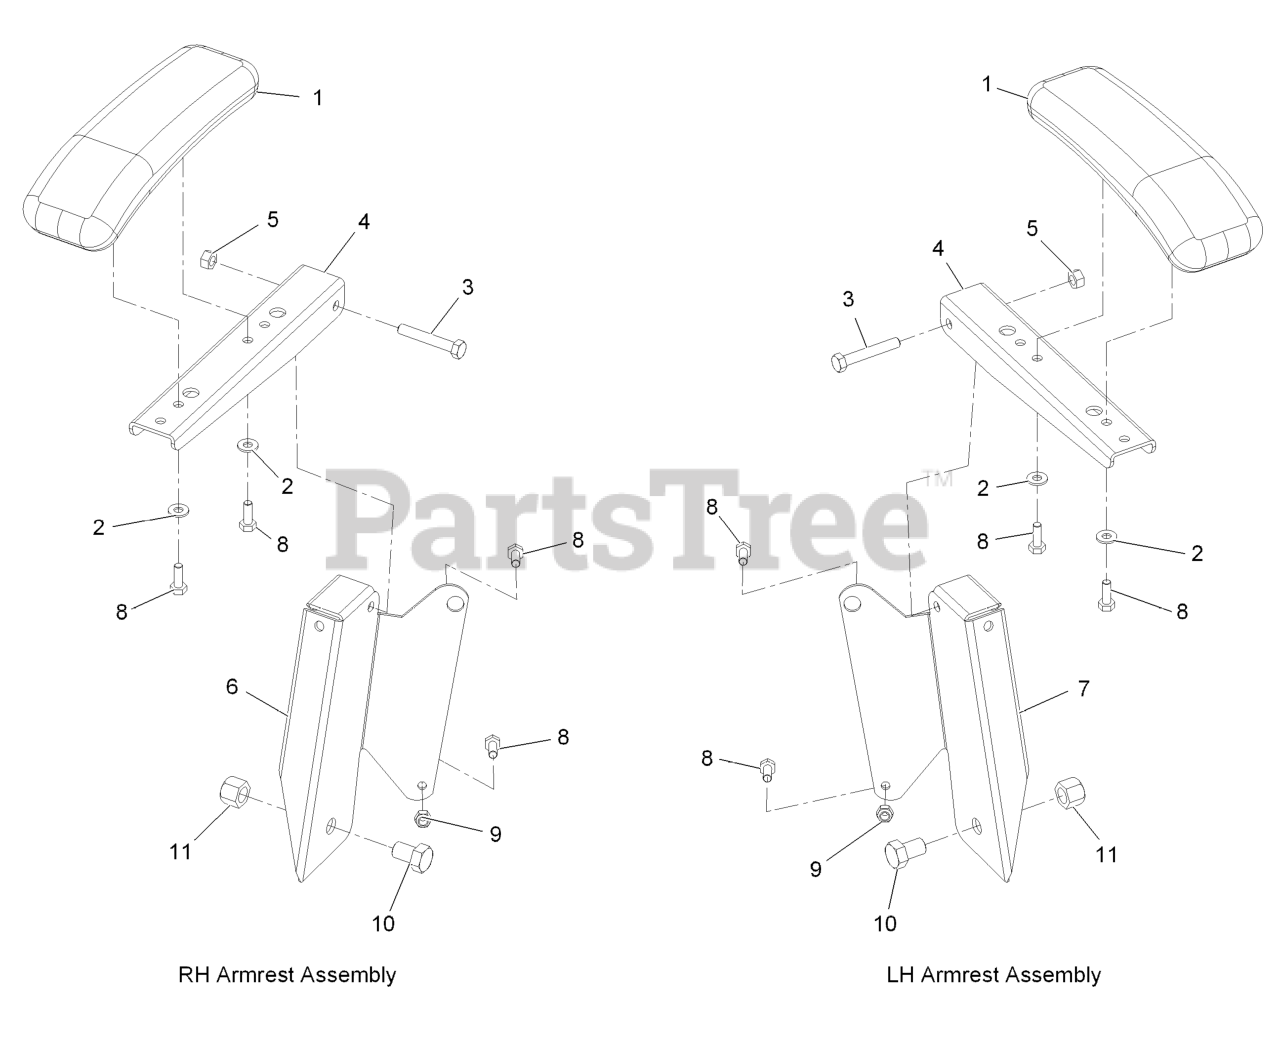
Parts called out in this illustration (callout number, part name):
1	CUSHION-REST, ARM
2	WASHER-FLAT
3	SCREW-HH
4	CHANNEL-ARMREST
5	NUT-HEX, SIDE DEFORM
6	BRACKET-ARMREST, RH
7	BRACKET-ARMREST, LH
8	SCREW-HH
9	NUT-LOCK, NI
10	SCREW-HH
11	NUT-LOCK, NI
